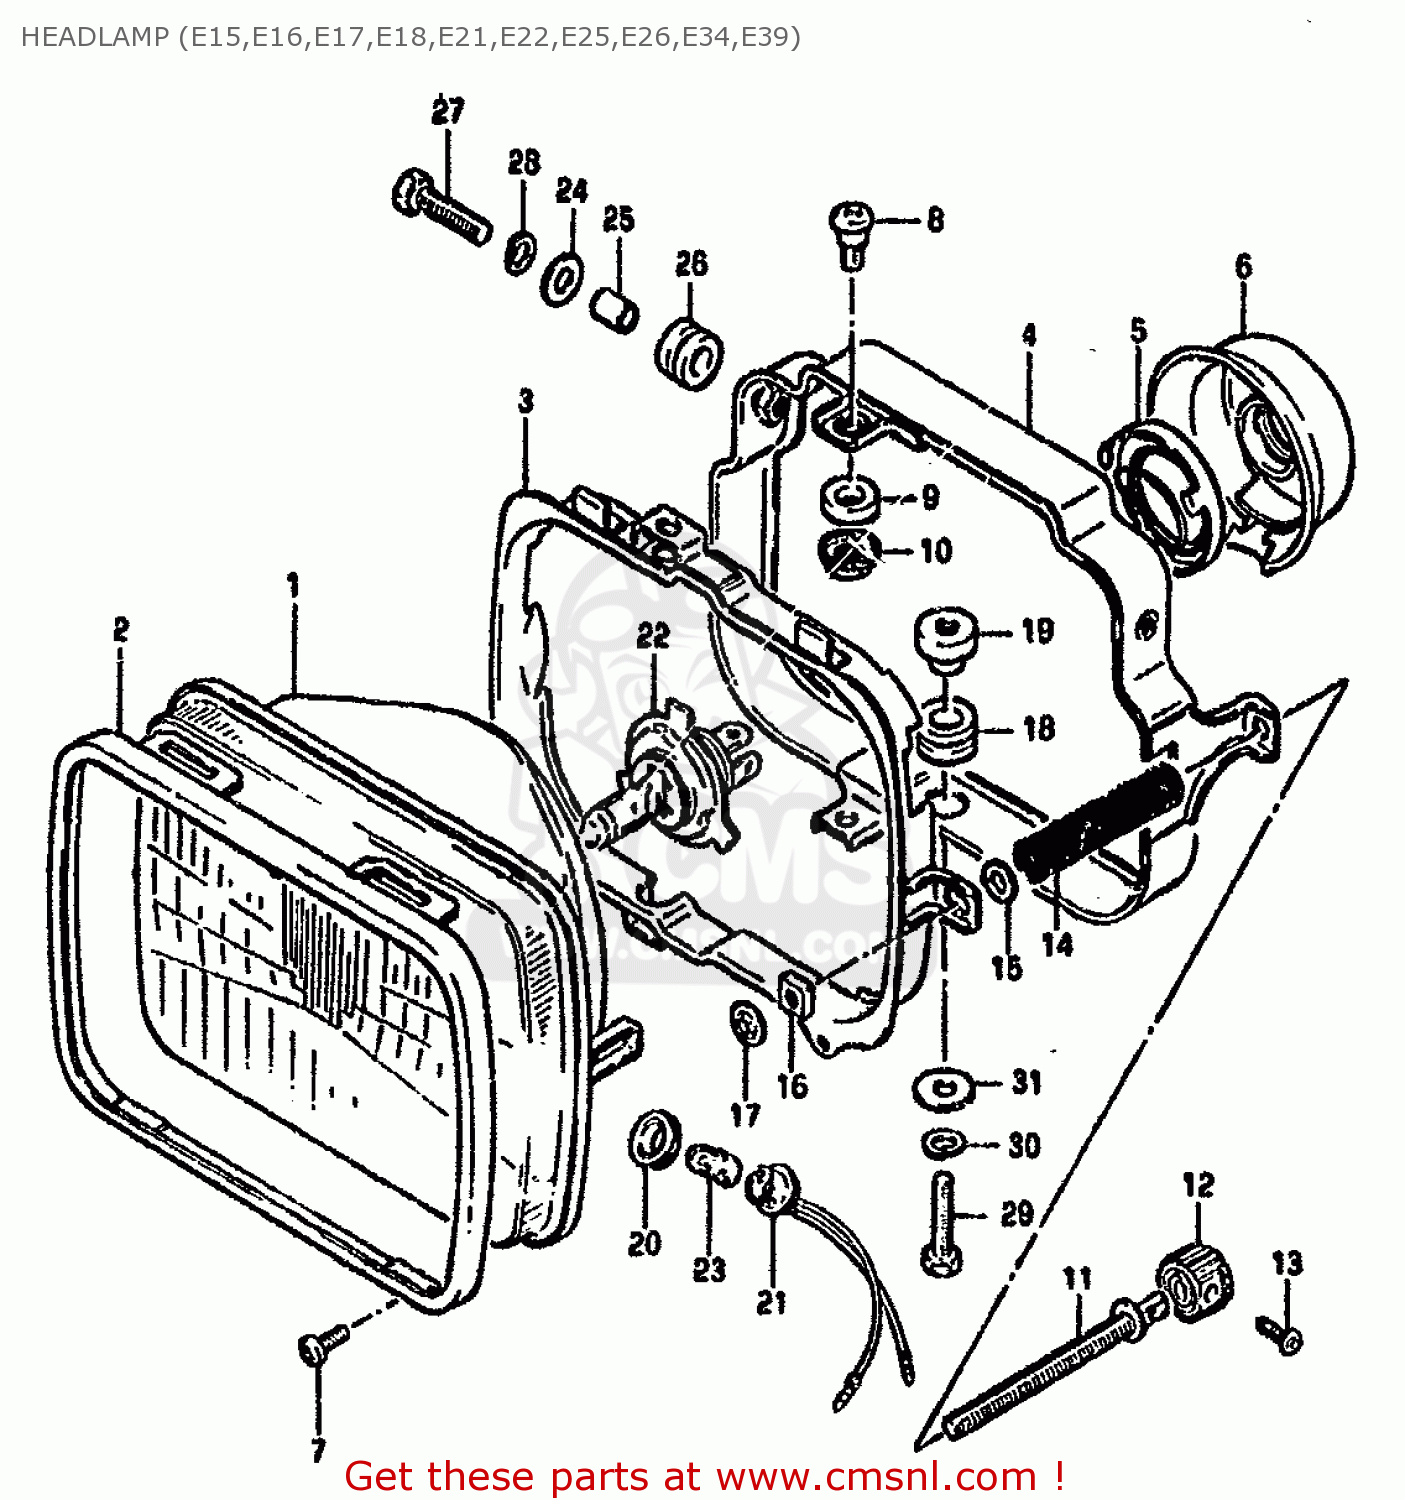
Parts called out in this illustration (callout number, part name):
1	LAMP UNIT
2	RETAINER
3	RING,MOUNTING
4	HOUSING
5	HOLDER, BULB
6	COVER,HEADLAMP SOCKET
7	SCREW
8	SCREW
9	SPACER
10	NUT,ADJUSTING
11	SCREW,ADJUSTING
12	KNOB,ADJUSTER
13	SCREW
14	SPRING
15	WASHER
16	NUT
17	NUT,HEADLAMP ADJUSTER
18	CUSHION
19	NUT
20	JOINT,RUBBER
21	SOCKET
22	BULB(12V60/55W,H4)
23	BULB(12V4W)
24	WASHER
25	SPACER (6.1X8X9.5)
26	CUSHION
27	BOLT
28	LOCK WASHER
29	SCREW(6X20)
30	LOCK WASHER
31	WASHER
